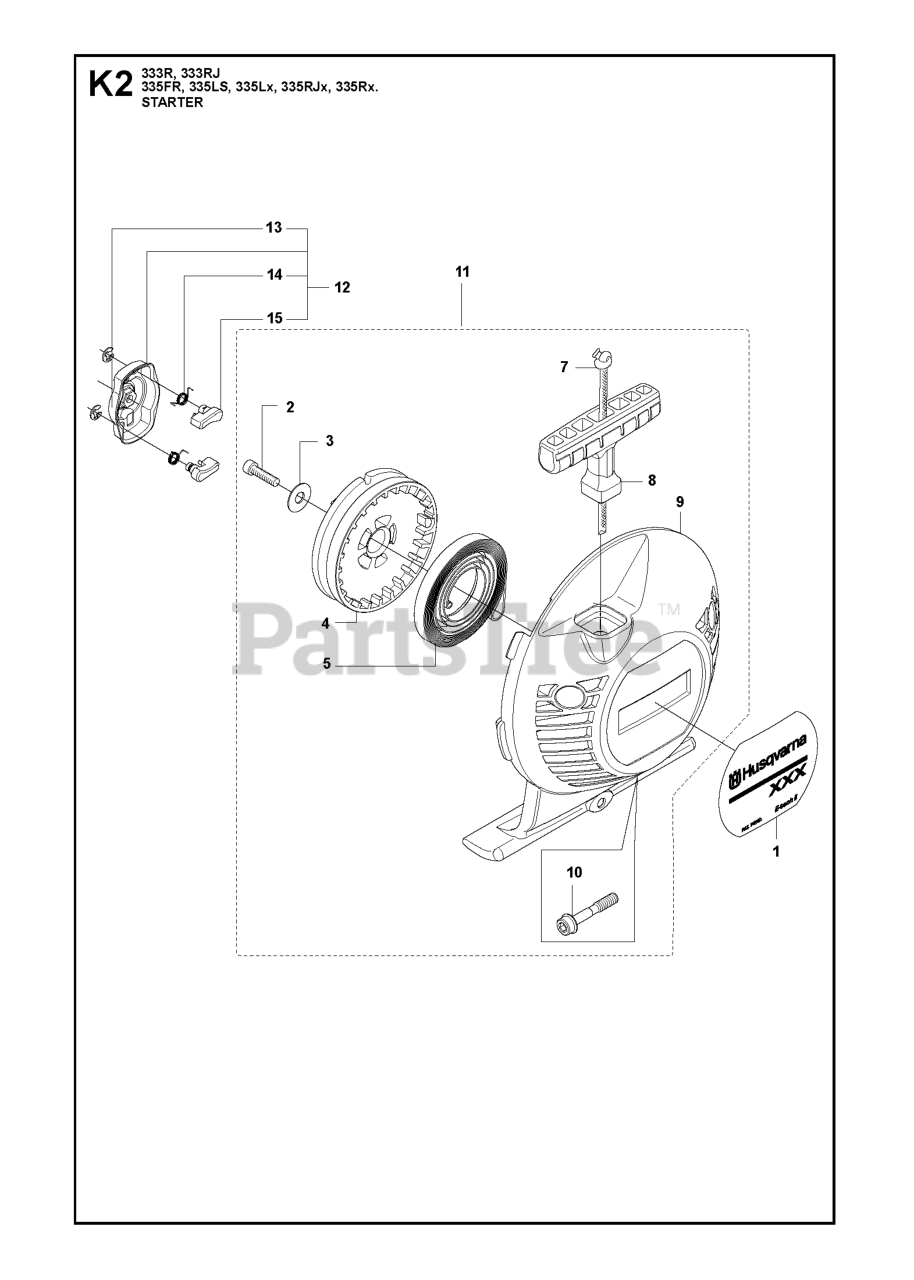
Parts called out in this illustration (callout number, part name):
1	DECAL
1	RP DECAL
1	LABEL
4	%STARTER PULLEY
5	STARTER SPRING
7	STARTER ROPE
8	STARTER HANDLE
9	STARTER
10	SCREW IHSCFMO
11	STARTER ASSY
12	STARTER PAWL BRIDGE
15	STARTER PAWL
